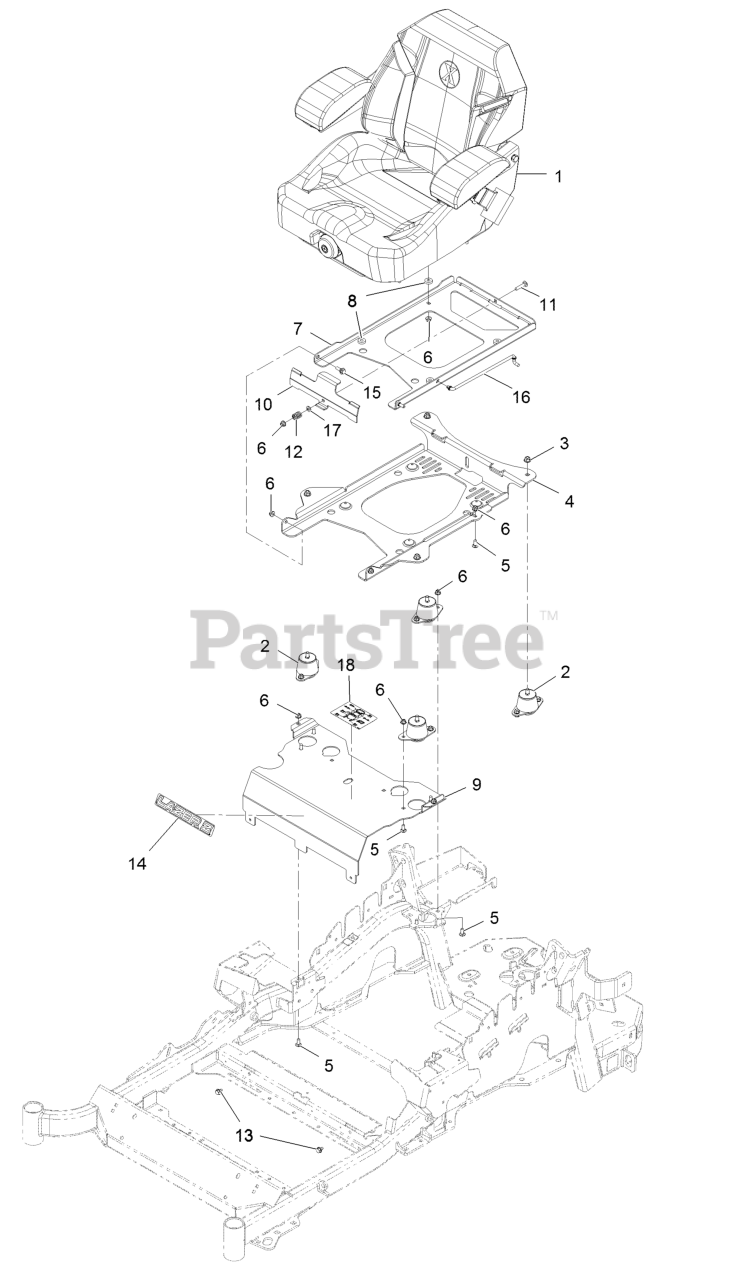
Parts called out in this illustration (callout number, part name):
1	Kit-Suspension Seat
2	Isolator-Seat
3	Nut-Nyloc 3/8-16 Flg
4	Plate-Tilt, Seat Support
5	Bolt-Carriage 5/16-18 X 3/4 Short Neck
6	Nut-Nyloc 5/16-18 Flg
7	Plate-Frame, Seat
8	Spacer-Pin, Mounting
9	Panel-Front, Seat Mount
10	Plate-Latch, Seat
11	Bolt-Carriage 5/16-18 X 1 1/2
12	Spring-Compression
13	Screw-HWH 5/16 X 1/2 Tf
14	Decal, Lazer Model
15	Screw-Shoulder
16	Rod-Prop
17	Washer-5/16 SAE
18	Decal-Service Aid
